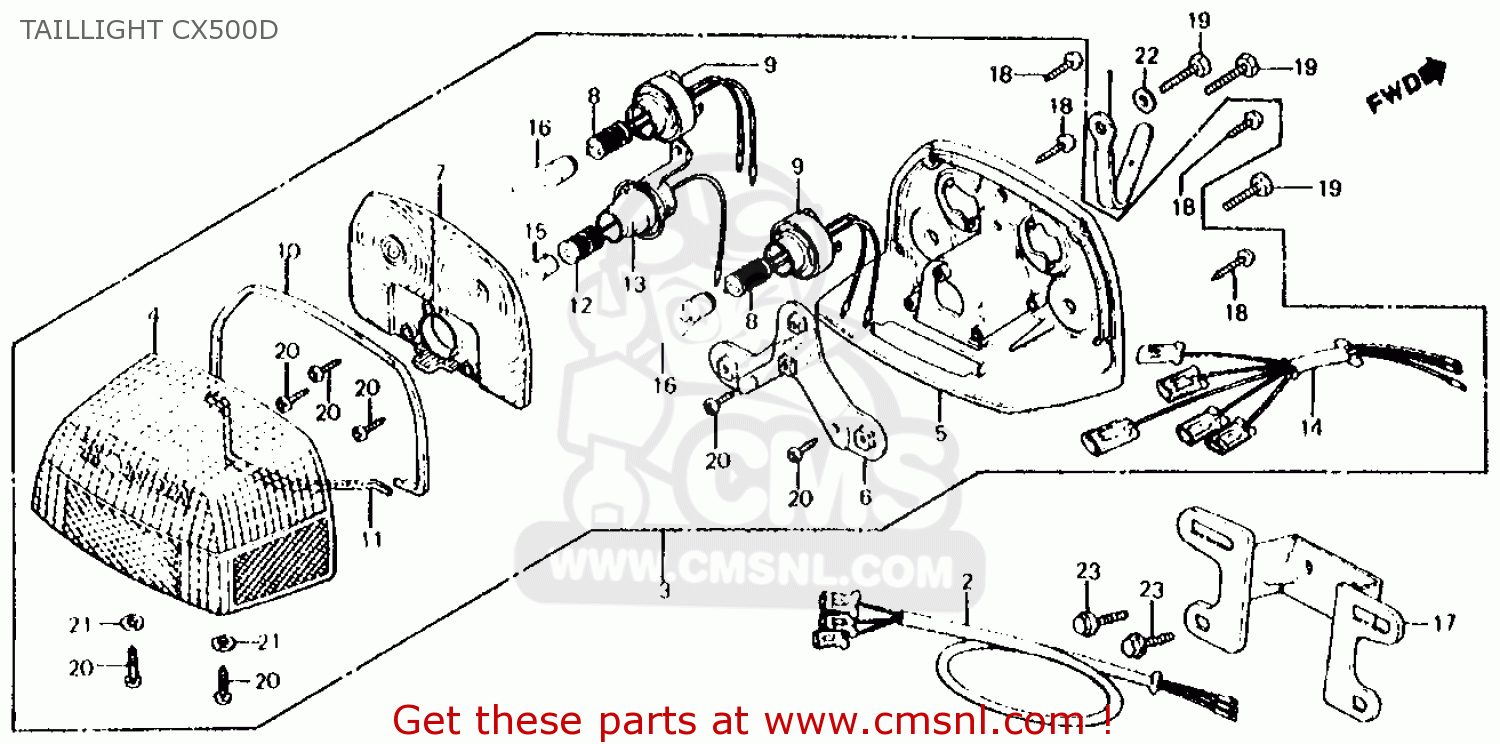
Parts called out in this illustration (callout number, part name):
1	CLAMPER,CORD
2	SUB HARNESS TAIL
3	TAILLIGHT ASSY.
4	LENS,TAILLIGHT
5	BASE,TAILLIGHT
6	STAY,TAILLIGHT
7	LENS, TAILLIGHT SUB
8	CORD COMP.,TAIL
9	SOCKET,TAILSTOP
10	PACK LIGHT LENS
11	PACK B LIGHT LENS
12	CORD,LICENSELIGHT
13	SOKET,LICENSE LIG
14	SUB CORD TAILLGHT
15	BULB
16	BULB,TAIL LIGHT
17	BKT,NUMBER PLATE
18	SCREW,TAP.4X18
19	BOLT,TAILLIGHT
20	SCREW,TAPPING4X12
21	WASHER,4MM
22	WASHER PLAIN 6MM
23	BOLT,FRANG,6X18
